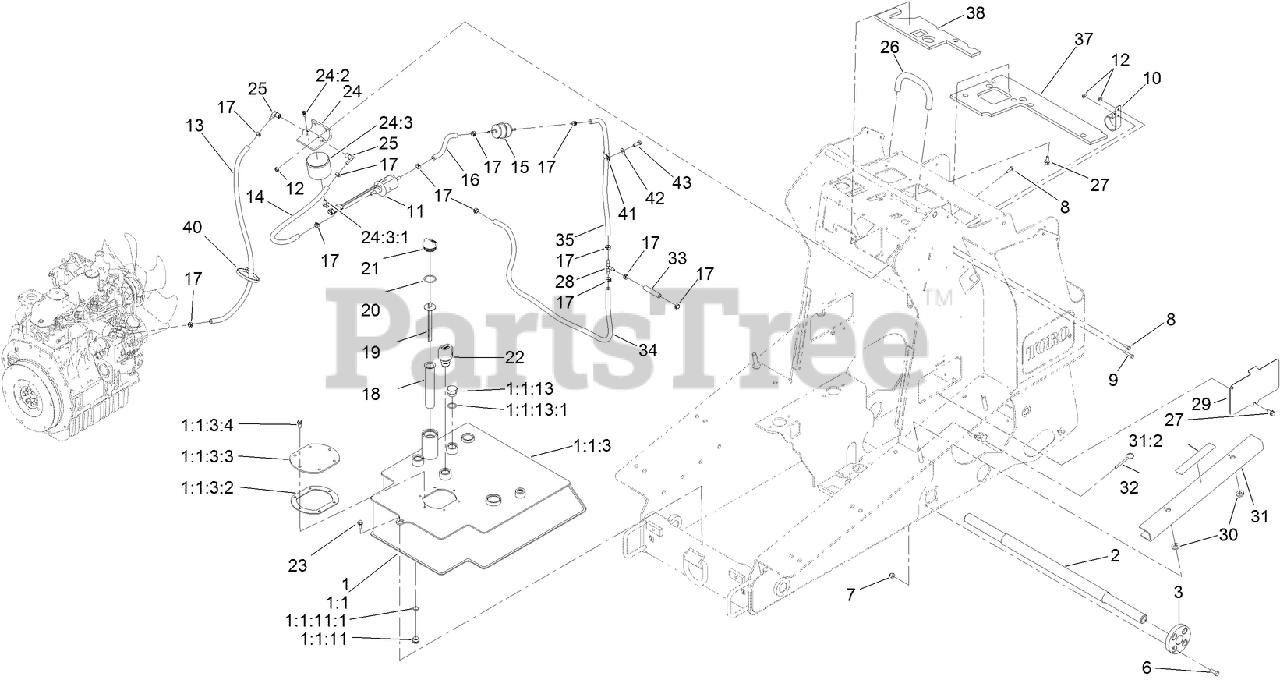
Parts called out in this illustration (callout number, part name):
1	HYD TANK ASM
1:1	TANK-HYD
1:1:3	TANK TOP ASM
1:1:3:2	GASKET-COVER, ACCESS
1:1:3:3	COVER-TANK
1:1:3:4	SCREW
1:1:11	PLUG-HEX
1:1:11:1	O-RING
1:1:13	PLUG-HH
1:1:13:1	O-RING
2	SHAFT-TRACK
3	HUB-SHAFT
6	SCREW-HH
7	NUT-LOCK, NI
8	SCREW-HH
9	SCREW-HH
10	BRACKET-PUMP, FUEL
11	PUMP-FUEL
12	NUT-HF
13	HOSE-FUEL
14	HOSE-FUEL
15	FILTER-INLINE
16	HOSE-FUEL
17	CLAMP-HOSE
18	FILTER-SCREEN
19	DIPSTICK
20	O-RING
21	PLUG-PLASTIC
22	BREATHER
23	SCREW-HWHTF
24	FILTER HEAD ASM
24:2	VENT-AIR
24:3	ELEMENT-SPIN ON
24:3:1	VALVE-DRAIN
25	FITTING-ELBOW
26	BAR-REFERENCE
27	SCREW-HHF
28	FITTING-TEE, BARBED
29	PLATE-COVER, ACCESS
30	WASHER-NEOPRENE
31	ARM-LOCKING
31:2	DECAL-DANGER
32	PIN-COTTERLESS
33	HOSE-FUEL
34	HOSE-FUEL
35	HOSE-FUEL
37	FOAM-HEAT SHIELD
38	FOAM-HEAT SHIELD
40	TIE-CABLE
41	CLAMP-R
42	WASHER-FLAT
43	SCREW-HH
